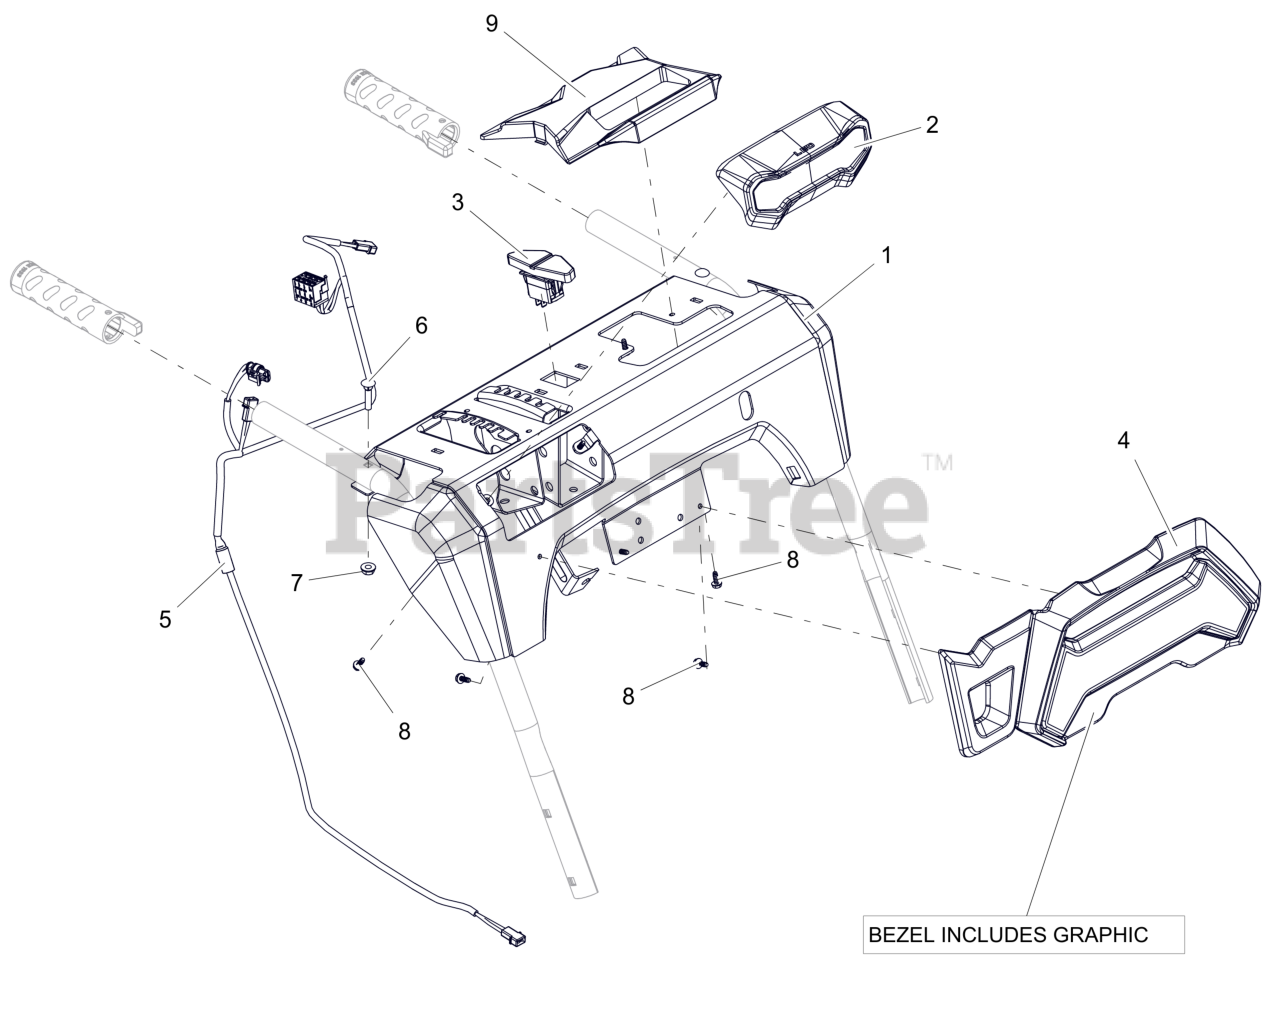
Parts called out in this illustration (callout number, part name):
1	PANEL, CONTROL W/SAFETY DECALS
2	HEADLIGHT ASM- LED
3	SWITCH, ROCKER W/SAFETY DECALS
4	BEZEL- LARGE - PLATINUM
5	HARNESS- WIRE - LT HG
6	BLT-RDHDXLSQNK.25-20X1.25 G5ZC
7	NUT-LK-CTR-FLG .25-20 ZC120
8	SCR, PLASTIC #10X.50
9	BEZEL, OPERATOR W/SAFETY DECALS
